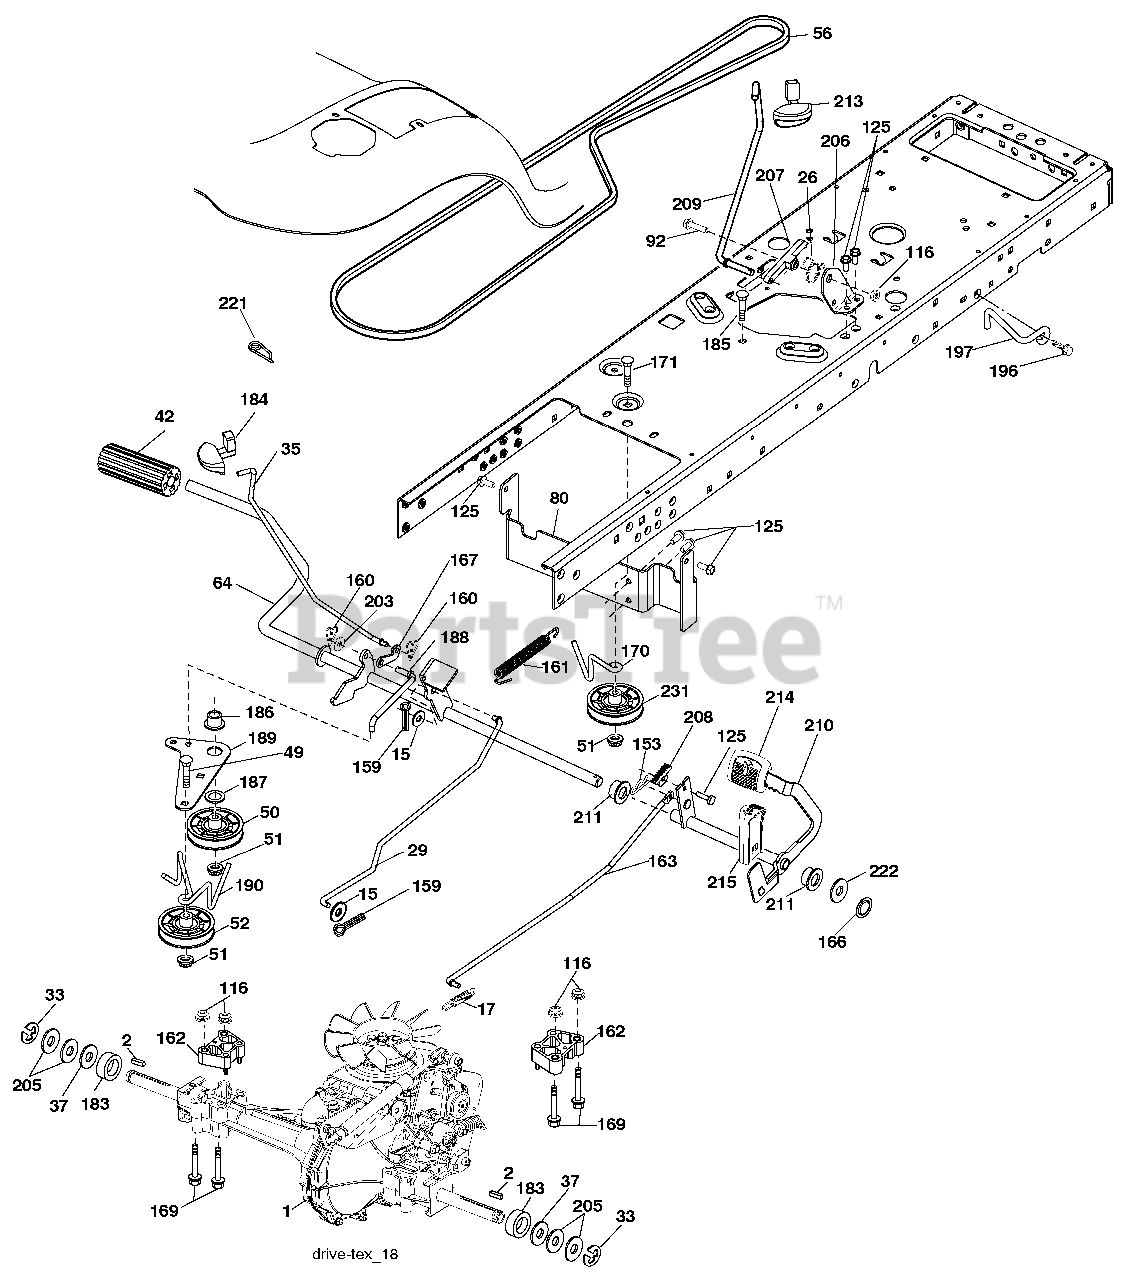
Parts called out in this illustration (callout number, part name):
2	Key
15	Washer 13/32 x 13/16 x 16 Ga.
17	Spring, Brake
26	Spring Return Cruise
29	Rod, Brake
33	Ring E
35	Rod, Brake, Park
37	Washer 25/32 x 1-1/4 x 16 Ga.
42	Cover, Foot Pedal
49	Bolt
50	Pulley Idler Flat
51	Lock Nut 3/8-16
52	Idler V-Groove 910" Offset
56	V-Belt, Drive
64	Shaft Asm. Pedal Brake Control
80	Bracket Strap Torque
92	Bolt Fin Hex 5/16-18 unc x 1.25
116	Nut Lock Hex Flange 5/16-18
125	Screw 5/16-18 x 3/4
153	Retainer Spring
159	Pin Cotter 1/8 x 3/4
160	Retainer Clip
161	Spring, Return, Clutch
162	Spacer Transaxle
163	Rod Pedal Control
166	Nut Push .625
167	Latch Brake Parking
169	Bolt Hex 5/16-18 x 3.75
170	Keeper Belt Centerspan
171	Bolt
183	Spacer Axle
184	Handle Parking Brake
185	Bolt
186	Spacer Retainer
187	Washer
188	Link Clutch Ground Drive
189	Bellcrank Ground Drive
190	Keeper Bellcrank Ground Drive
196	Screw 3/8-16 x 1
197	Link Clutch Anti-Rotation
203	Washer 11/32 x 11/16 x 16 Ga.
205	Washer 25/32 x 1-5/8 x 16 Ga.
206	Bracket Mount Latch Cruise
207	Latch Control Cruise
208	Gear Sector Control Cruise
209	Rod Control Cruise
210	Rockr Asm. Pdeal Control
211	Bearing Nylon
213	Knob control Cruise
214	Pad Pedal Forward
215	Pad Pedal Reverse
222	Washer 21/32 x 1-1/4 10 Ga.
231	Idler V-Groove
